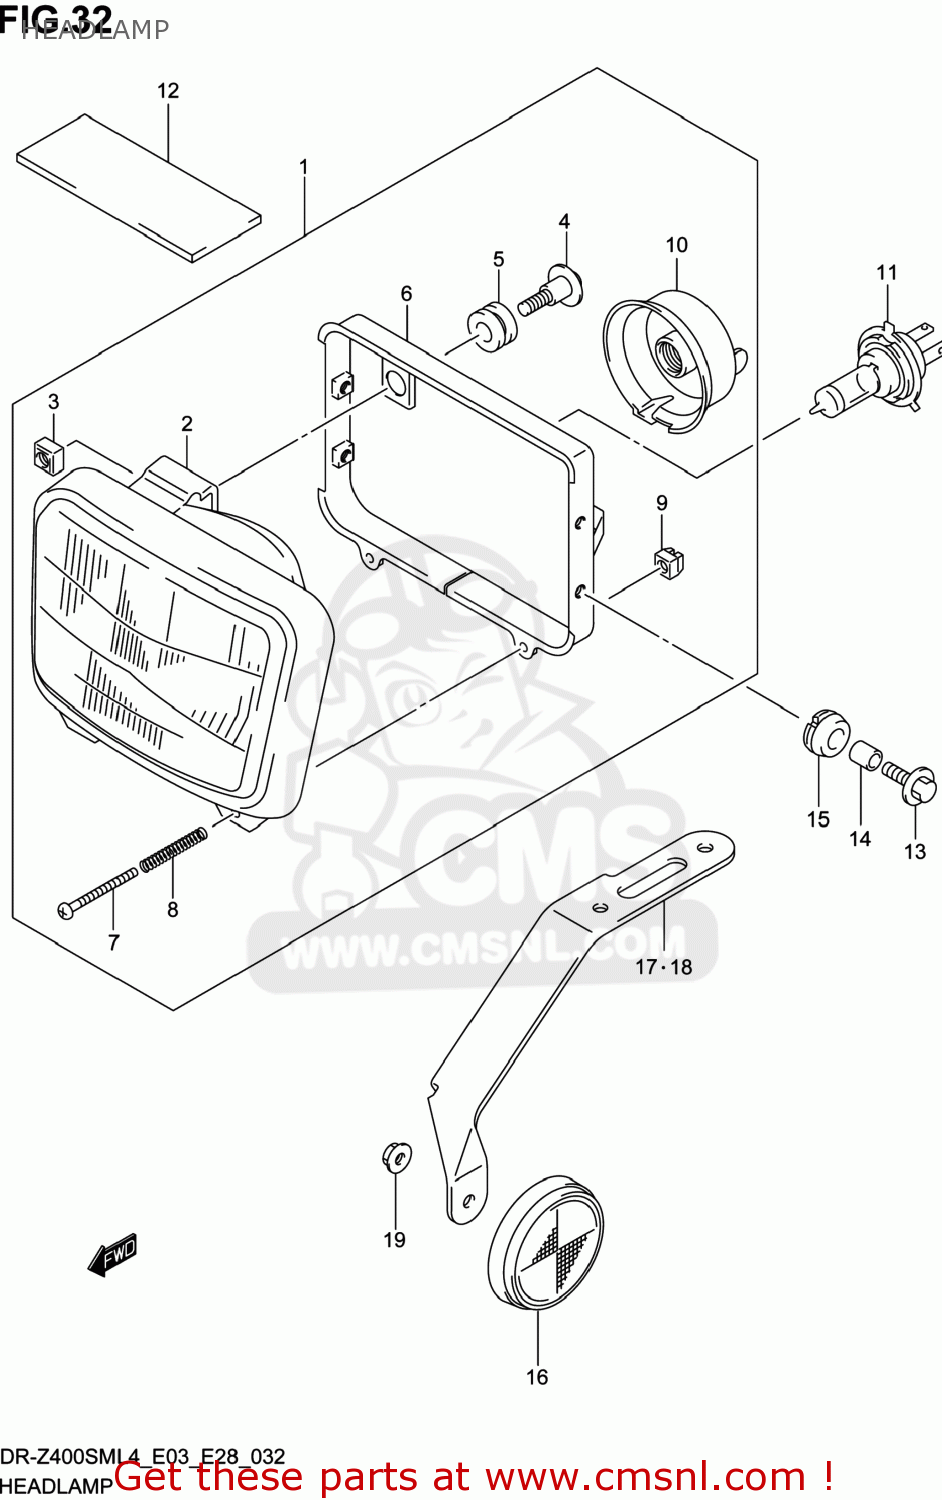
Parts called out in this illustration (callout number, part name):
1	HEADLAMP ASSY
2	UNIT ASSY
3	NUT
4	SCREW,MOUNTING
5	CUSHION
6	HOUSING
7	SCREW,ADJUSTING
8	SPRING,ADJUSTING
9	NUT,ADJUSTING
10	COVER,SOCKET
11	BULB(12V60/55W,H4)
12	PROTECTOR,WIRING HARNESS
13	BOLT(6X20)
14	SPACER(6.5X10X10)
15	CUSHION
16	REFLEX REFLECTOR ASSY,FR SIDE
17	BRACKET,FR SIDE RR,R
18	BRACKET,FR SIDE RR,L
19	NUT
